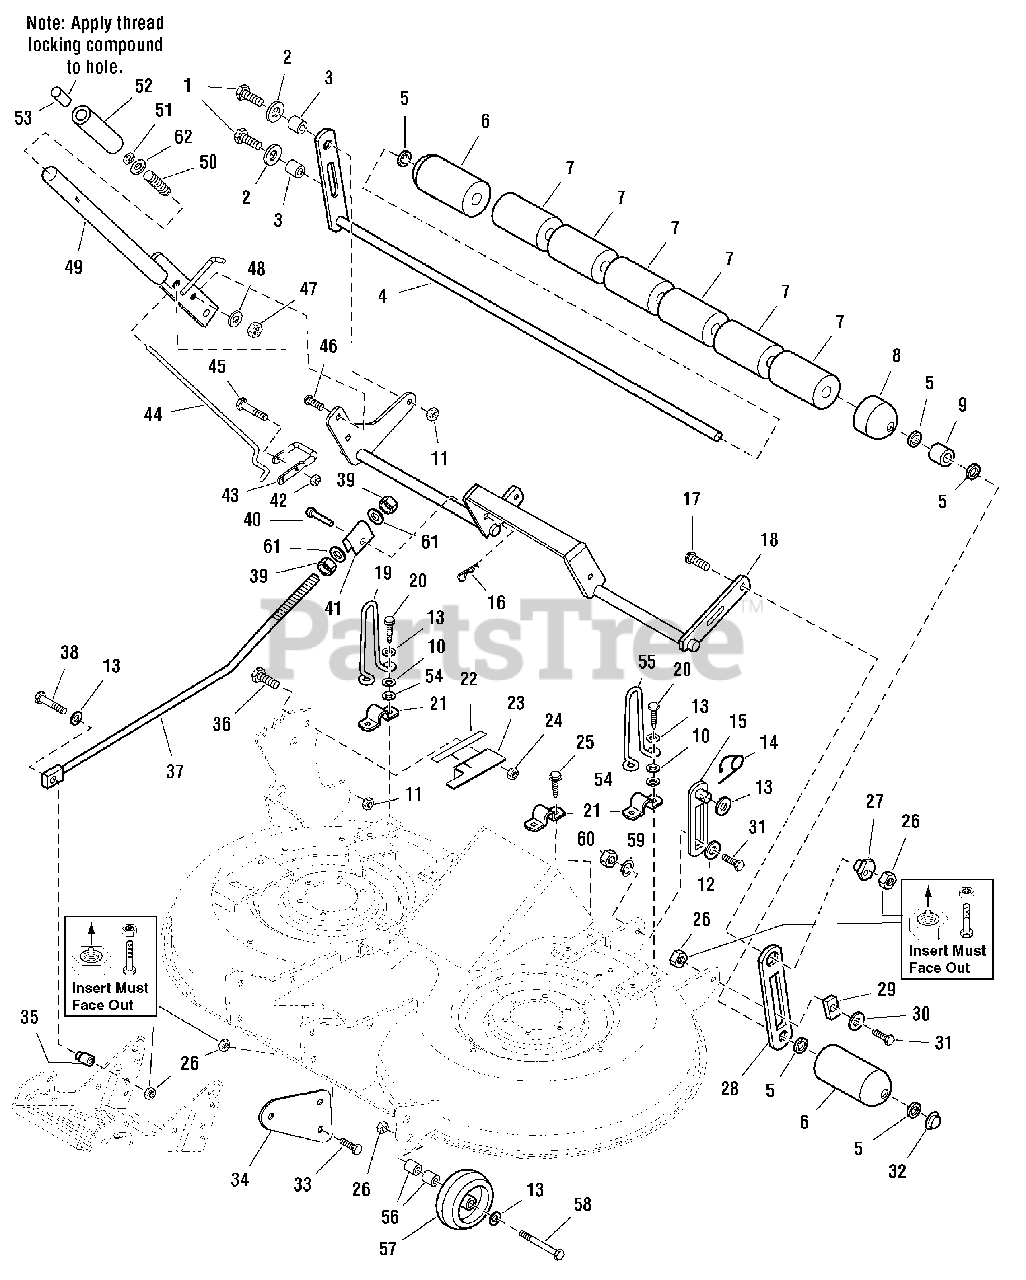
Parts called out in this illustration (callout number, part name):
1	CAPSCREW, Hex Head, 5/16-18 x 1-1/4
2	WASHER
3	SPACER
4	SHAFT & BAR ASSEMBLY
5	WASHER
6	ROLLER
7	ROLLER
8	ROLLER
9	SPACER
10	WASHER
11	NUT, Hex Flange Lock, 5/16-18
12	WASHER, 3/8
13	WASHER
14	RETAINER, Pin
15	LINK & PIN ASSEMBLY
16	PIN, Retaining
17	CARRIAGE BOLT, 3/8-16 x 1-1/2
18	SHAFT & ARM ASSEMBLY
19	STOP, Up
20	CAPSCREW, Hex Head Taptite, 5/16-18 x 1-1/4
21	STRAP
22	DECAL, Height of Cut
23	BRACKET, Height of Cut
24	NUT, Hex Lock ESNA Light, 5/16-18
25	CAPSCREW, Hex Head Taptite, 5/16-18 x 3/4
26	NUT, Hex Lock Aluminum Insert, 3/8-16
27	NUT, Hex Adjusting
28	BAR
29	SLIDE
30	WASHER
31	SHOULDER BOLT, 3/8-16
32	NUT, Push
33	CAPSCREW, Hex Head Whiz Lock, 3/8-16 x 1
34	SUPPORT, Hitch
35	SPACER
36	CAPSCREW, Hex Head, 5/16-18 x 3/4
37	ROD, Adjusting
38	CAPSCREW,Hex Head, 3/8-16 x 1-3/4, GR8
39	NUT, Hex, 5/8-11
40	PIN, Round Head Drilled, 3/8 x 2
41	TRUNNION
42	NUT, Hex Lock ESNA, 1/4-20
43	LATCH, "U"
44	ROD
45	CAPSCREW, Hex Head 1/4-20 x 2-1/4
46	BOLT, Carriage, Short Neck, 5/16-18 x 1
47	NUT, Hex, 5/16-18
48	LOCKWASHER, 5/16
49	HANDLE ASSEMBLY, Lift
50	SPRING, Compression
51	NUT, Push
52	GRIP, Black
53	BUTTON, Red
54	NUT, Push
55	UPSTOP
56	SPACER
57	WHEEL, Gauge
58	CAPSCREW, Hex Head, 3/8-16 x 3
59	LOCKWASHER, 3/3
60	NUT, Hex, 3/8-16
61	WASHER, 21/32 x 1 x 1/64
62	WASHER, 11/32 x 11/16 x 1/16
